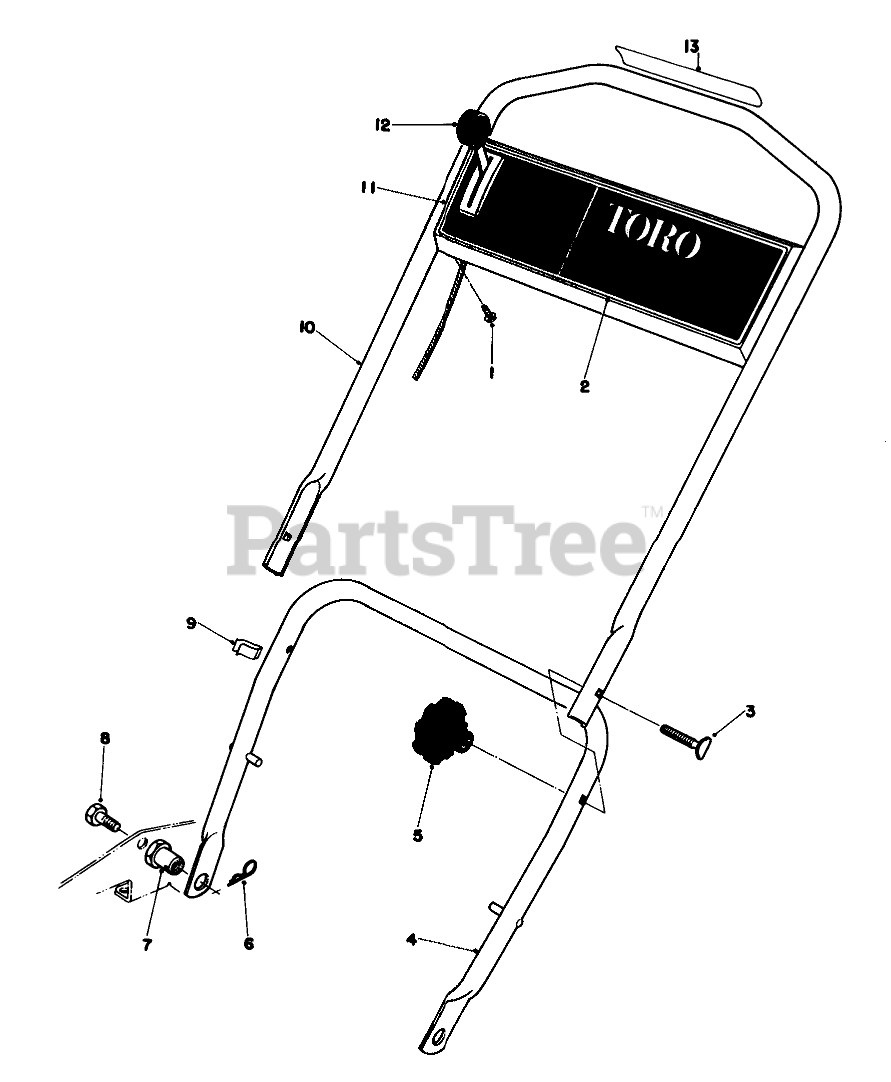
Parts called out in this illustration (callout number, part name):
1	SCREW-HWHTF
2	Decal Control Plate
3	SCREW-HANDLE
4	LOWER HANDLE ASM
6	PIN-COTTER, HAIR
7	HANDLE PIVOT NUT
8	SCREW-HH
10	UPPER HANDLE
11	Control Plate
12	Throttle Control
13	Decal-Instruction
